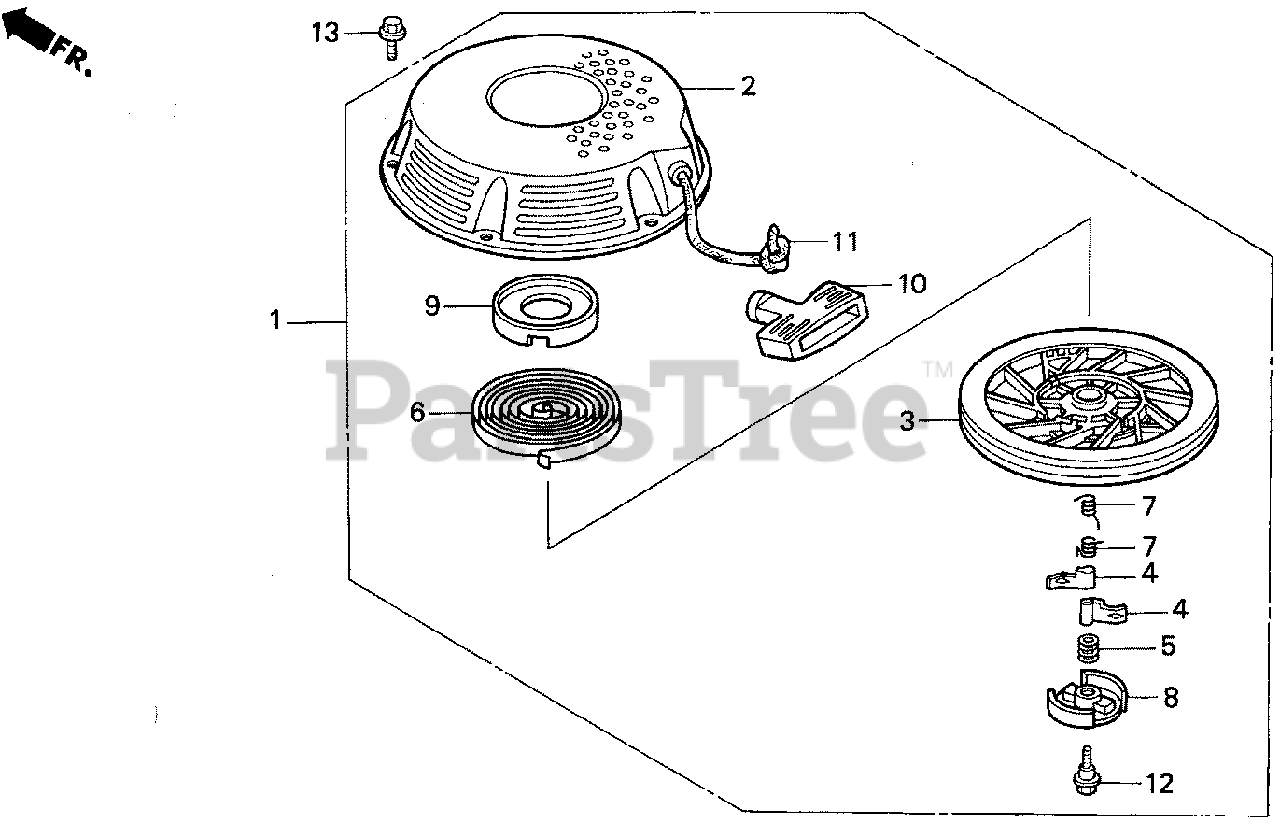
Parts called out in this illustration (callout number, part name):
1	STARTER ASSY., RECOIL *R8* (Honda Code 4186318). (BRIGHT RED)
1	STARTER ASSY., RECOIL *R280* (Honda Code 7660962). (POWER RED)
2	CASE, RECOIL STARTER *R8* (Honda Code 4186326). (BRIGHT RED)
3	PULLEY, RECOIL STARTER
4	RATCHET, STARTER
5	SPRING, FRICTION
6	SPRING, STARTER RETURN
7	SPRING, RATCHET
8	RETAINER, SPRING
9	HOLDER, SPRING
10	GRIP, STARTER
11	ROPE, RECOIL STARTER (#5X55") (Honda Code 3678968). (NA USE ALT:08550-ZG921-11)
12	SCREW, CENTER
13	BOLT, FLANGE (6X10)
14	GRIP, REINFORCEMENT
